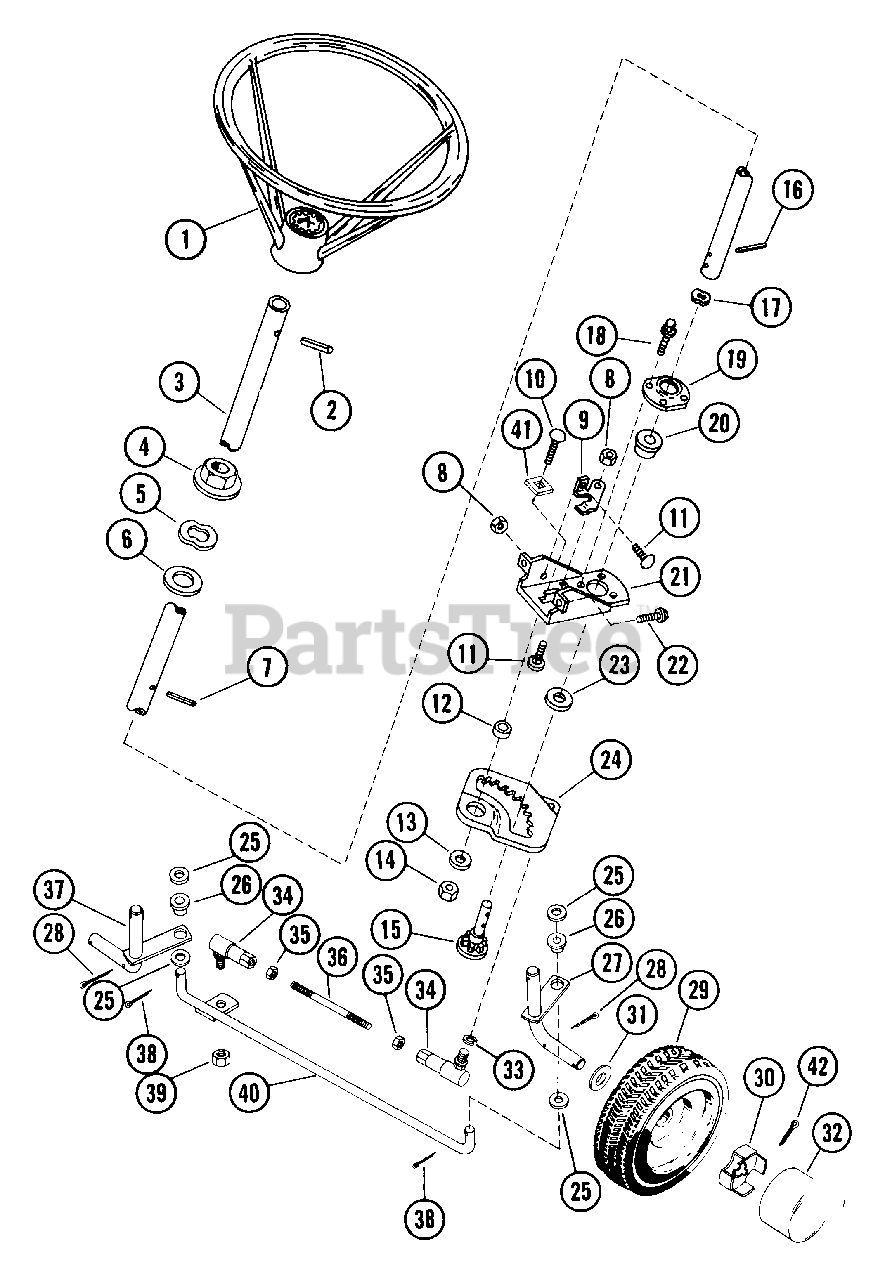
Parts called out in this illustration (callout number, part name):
1	STEERING WHEEL
2	PIN-ROLL .250X1.25
3	STEERING SHAFT
4	FLANGE BUSHING
5	SPRING WASHER
6	WSHR-FL-STL .755X1.375X.062 PL
7	PIN-ROLL .188X1.25
8	NUT-LK-CTR .250-20 PL
9	ADJUSTMENT BRACKET
10	BLT-RDHDSQSHNK .38-16X1.00 PL
11	BLT-RDHDSQNK .25-20X.62 PL
12	SPACER .380X.750X.236
13	WSHR-FL-STL .390X1.500X.125
14	NUT-LK-CTR .375-16 GR A PL
15	STEERING PINION
16	PIN-ROLL .188X1.00
17	WAVE WASHER .531X.781X.125FH
18	SCR-TAP 10-24X.25 CRSLPH PL 1A
19	RETAINING PLATE
20	BSHG-FLG .625X1.156X.375 SI
21	STEERING BRACKET
22	BLT-SERHFWH .31-18X.50 PL
23	WSHR-FL-STL .630X1.005X.062 PL
24	STEERING GEAR
25	WSHR-FL-STL .505X.875X.024 PL
26	BSHG-FLG.500X.625X.312X.750NY
27	L H WHEEL SPINDLE
28	PIN-COTR .12 X 1.25 PL
29	FRONT WHEEL ASSEMBLY
29	TIRE 4.10/3.50-4
29	WHL
29	ZERK FITTING
29	BSHG-FLG .750X1.380X.750X1.557
29	BRG-BALL .752X1.50X.50
30	SPINDLE CUP
31	SPINDLE WASHER
32	HUB CAP
33	WSHR-LK .375X.115 HVY PL
34	BALL JOINT
35	NUT .375-24 PL
36	STEERING LINK
37	R H WHEEL SPINDLE
38	PIN-COTR .12X1.0 PL
39	NUT-LK-CTR .375-24
40	TIE ROD
41	WASHER
42	PIN-COTR .12X1.0 PL
